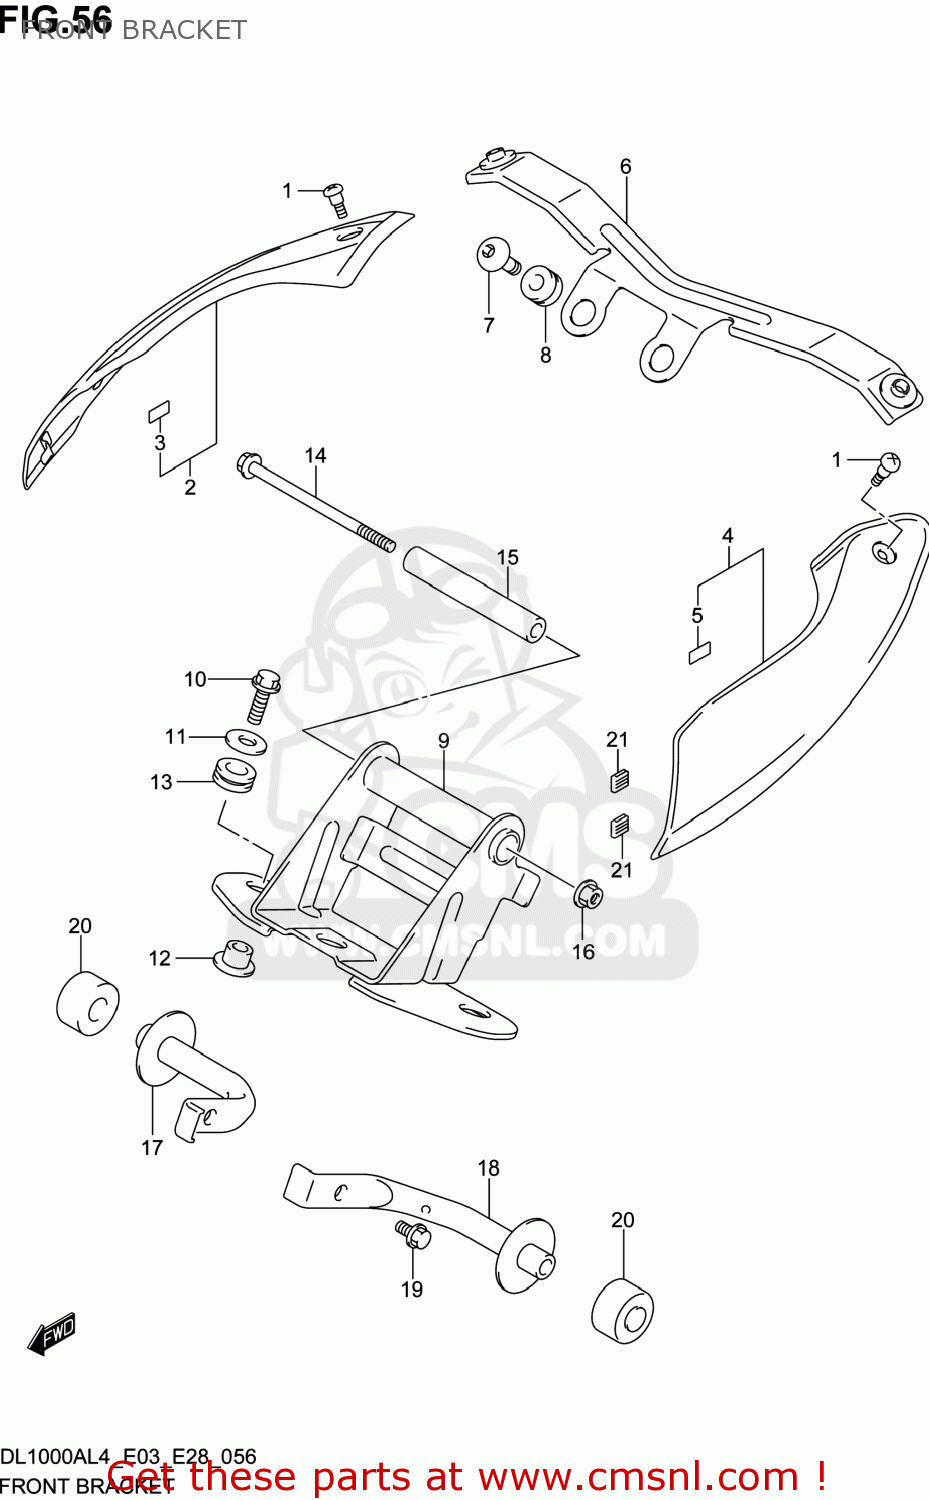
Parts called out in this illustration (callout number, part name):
1	SCREW(6X16)
2	COVER,SIDE REAR,R
3	CUSHION,COVER SIDE
4	COVER,SIDE REAR,L
5	CUSHION,COVER SIDE
6	BRACKET,FRONT COVER
7	BOLT(6X20)
8	CUSHION,FUEL TANK COVER BRKT
9	BRACKET,FUEL TANK FRONT
10	SCREW(6X25)
11	WASHER(6,5X22X1.6)
12	SPACER,FUEL TANK FR
13	CUSHION,FUEL TANK FR
14	BOLT
15	SPACER,FUEL TANK RR
16	NUT
17	BRACKET,FRONT SIDE
18	BRACKET,FRONT SIDE
19	BOLT
20	CUSHION,FRONT SIDE BRKT
21	GROMMET
